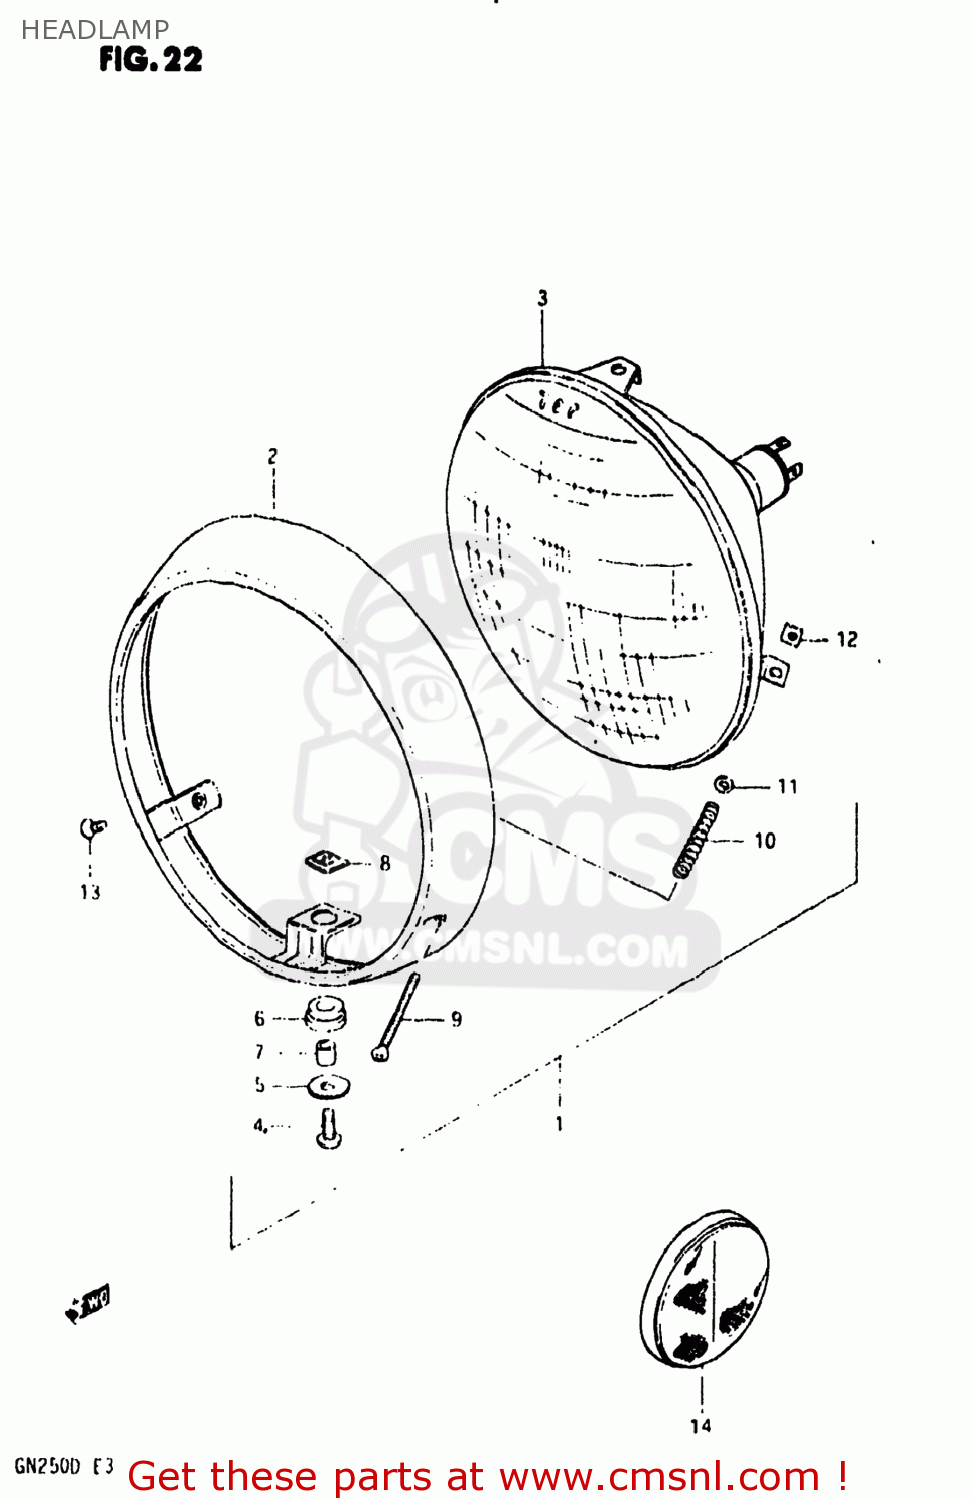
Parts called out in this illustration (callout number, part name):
1	LAMP ASSEMBLY,HEAD
2	RIM
3	LAMP UNIT
4	SCREW
5	WASHER
6	CUSHION
7	SPACER
8	NUT
9	SCREW
10	SPRING
11	WASHER
12	NUT,HEADLAMP ADJUSTER
13	SCREW(5X12)
14	REFLEX REFLECTOR,RR
